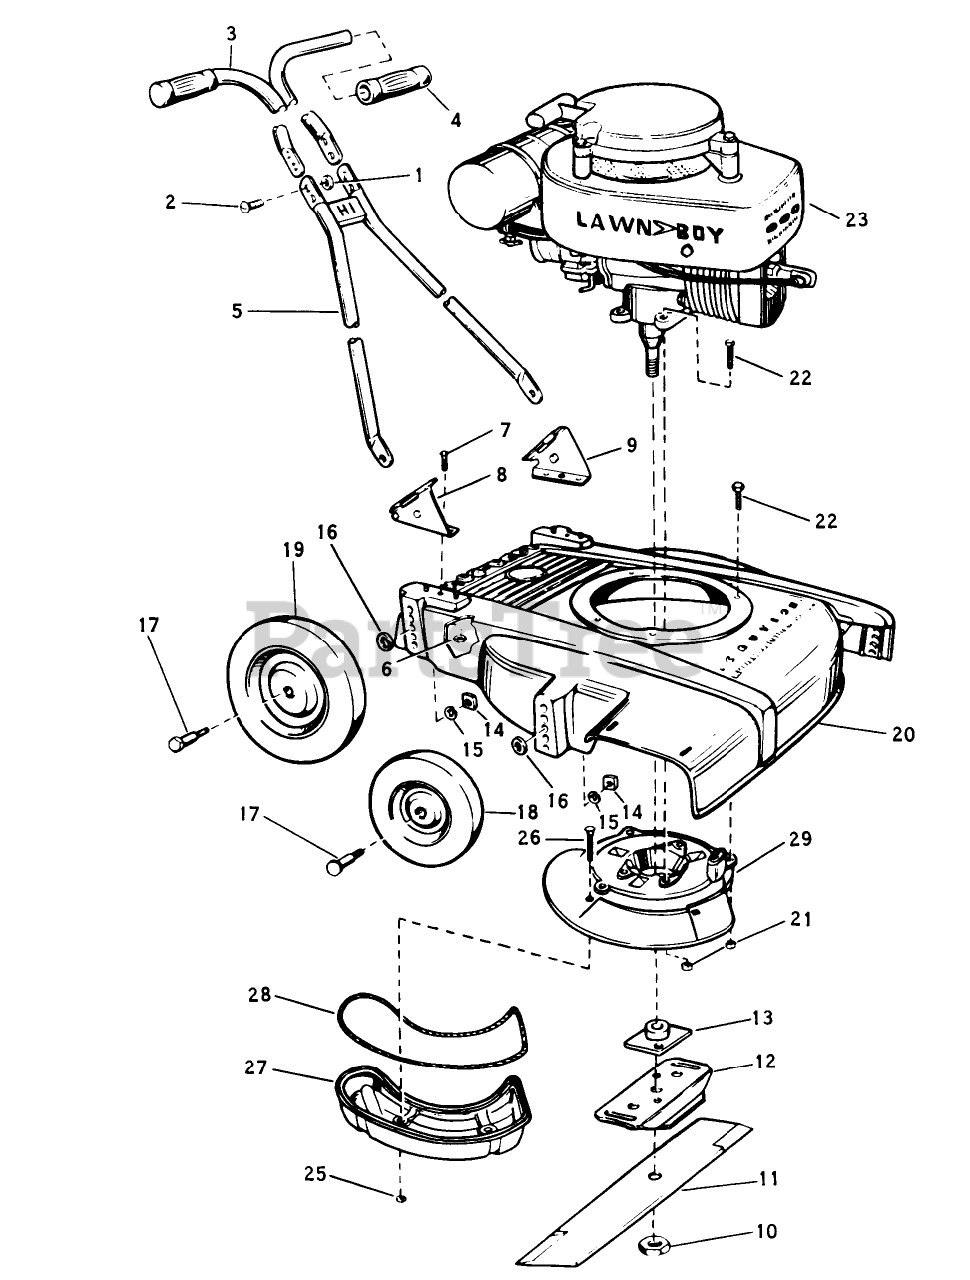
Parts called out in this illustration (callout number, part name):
1	STOP NUT
4	HANDLE GRIP
10	NUT-BLADE
13	PLATE AND COLLAR ASM
15	WASHER, LOCK
16	WASHER WROUGHT
20	Housing-18"
25	LOCKNUT E
